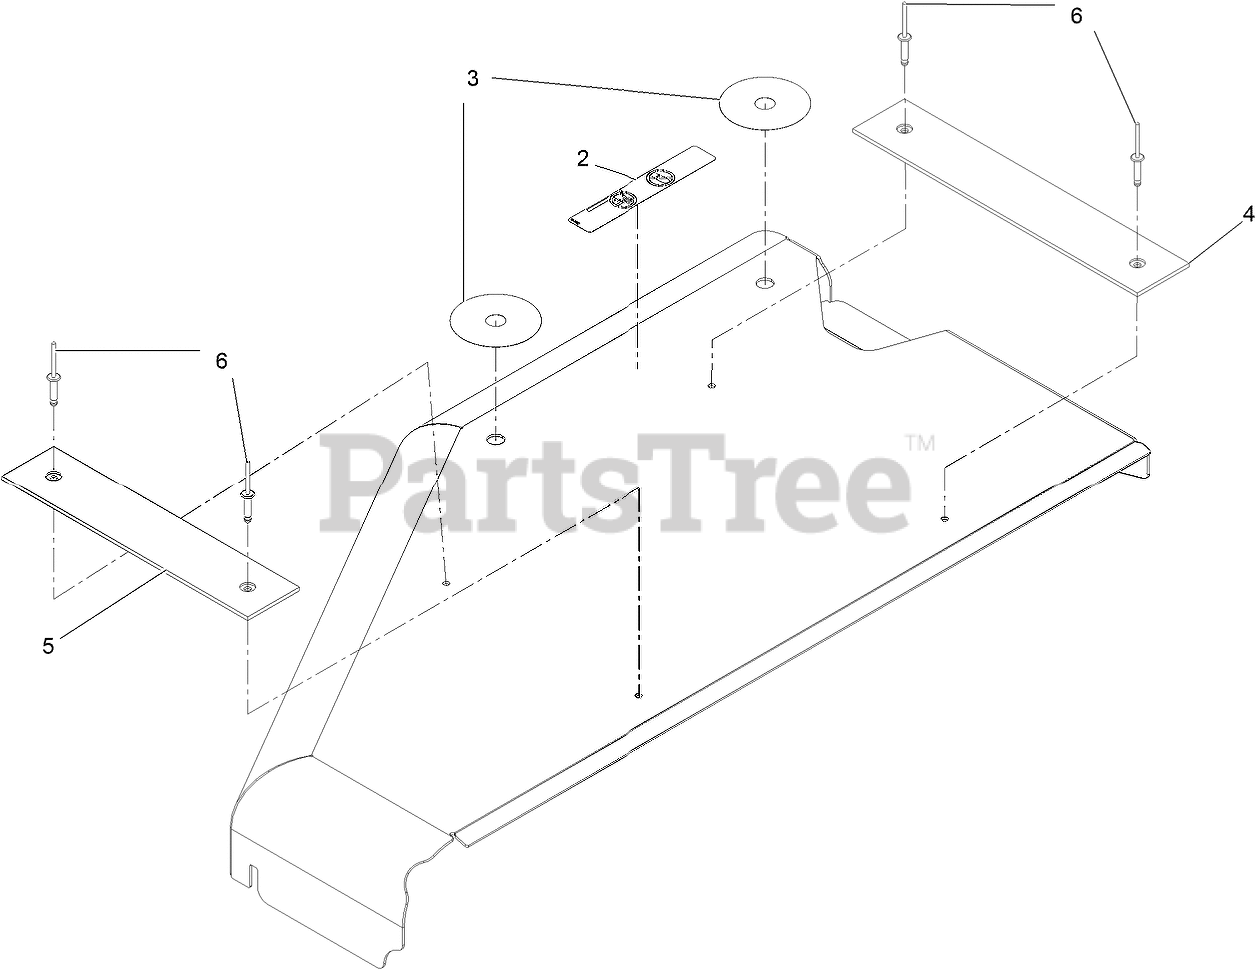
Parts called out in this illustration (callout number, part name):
2	DECAL-NO STEP
3	DECAL-SCRATCH COVER
4	Plate-Uhmw 2"
5	PLATE-FRONT
6	Rivet-Pop
